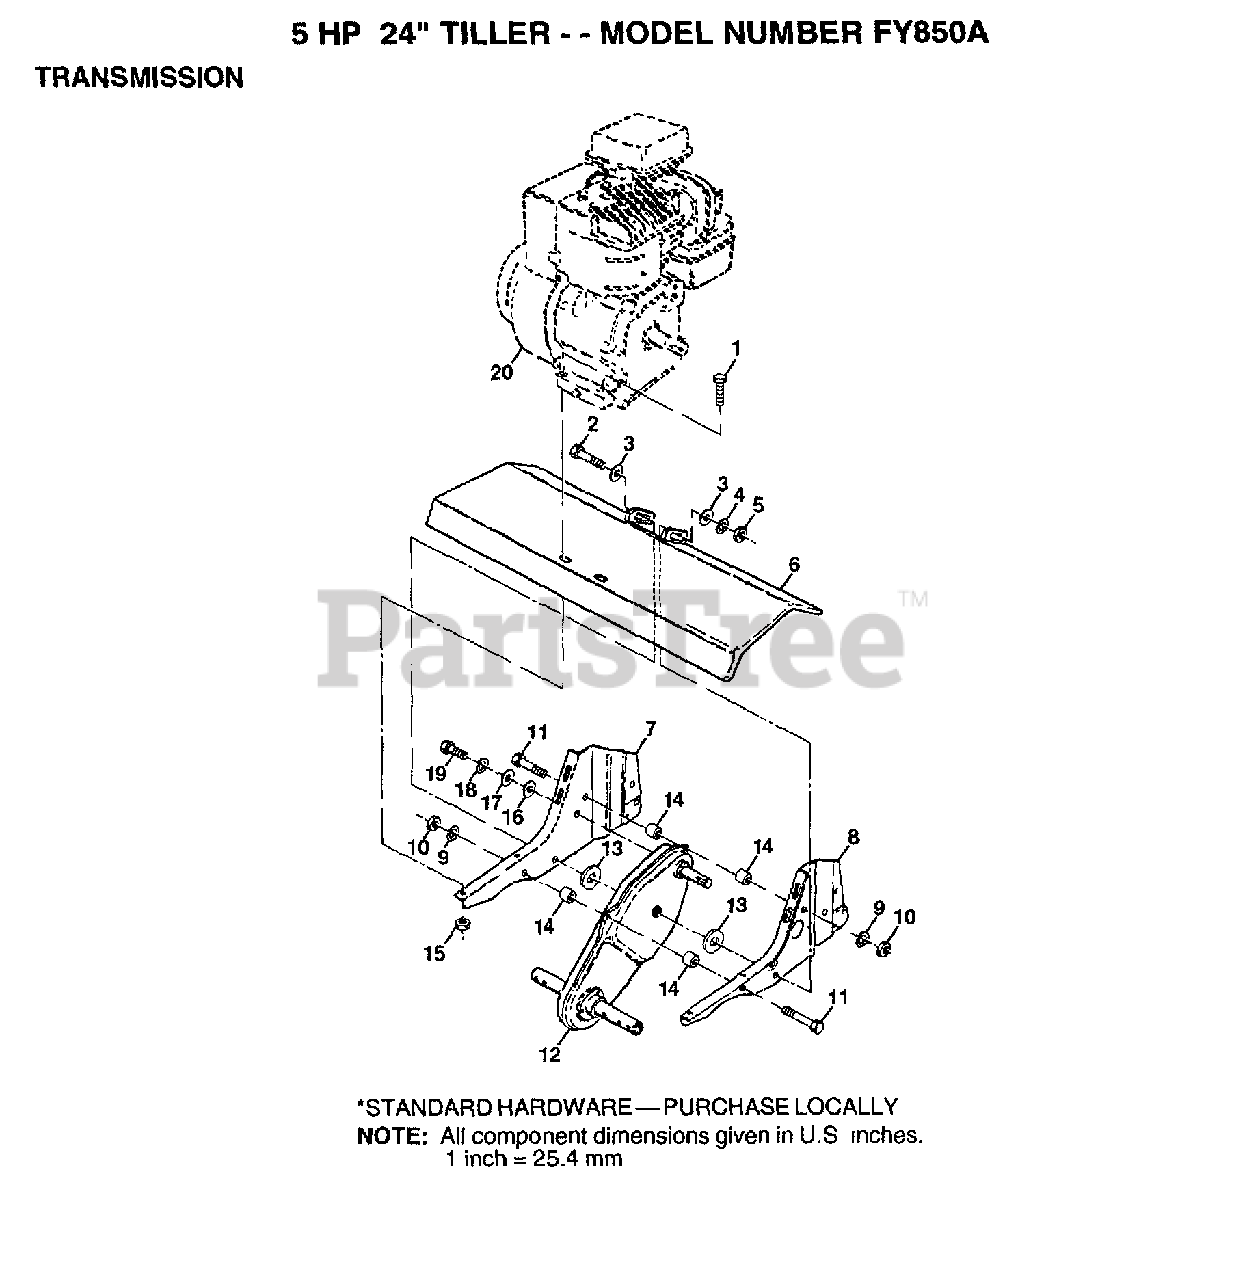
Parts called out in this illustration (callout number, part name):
1	BOLT.HEX.5/16-1.5
2	BOLT.3/8-24X3.75
3	WASHER
4	LOCKWASHER
5	GRIPCO NUT
6	"SHIELD, TINE"
8	BRACKET.ENG.LH.
9	LOCKWASHER
10	NUT.HEX.5/16-18
14	SPLIT SPACER RT
16	WASHER
17	WASHER
18	LOCKWASHER
19	BOLT
